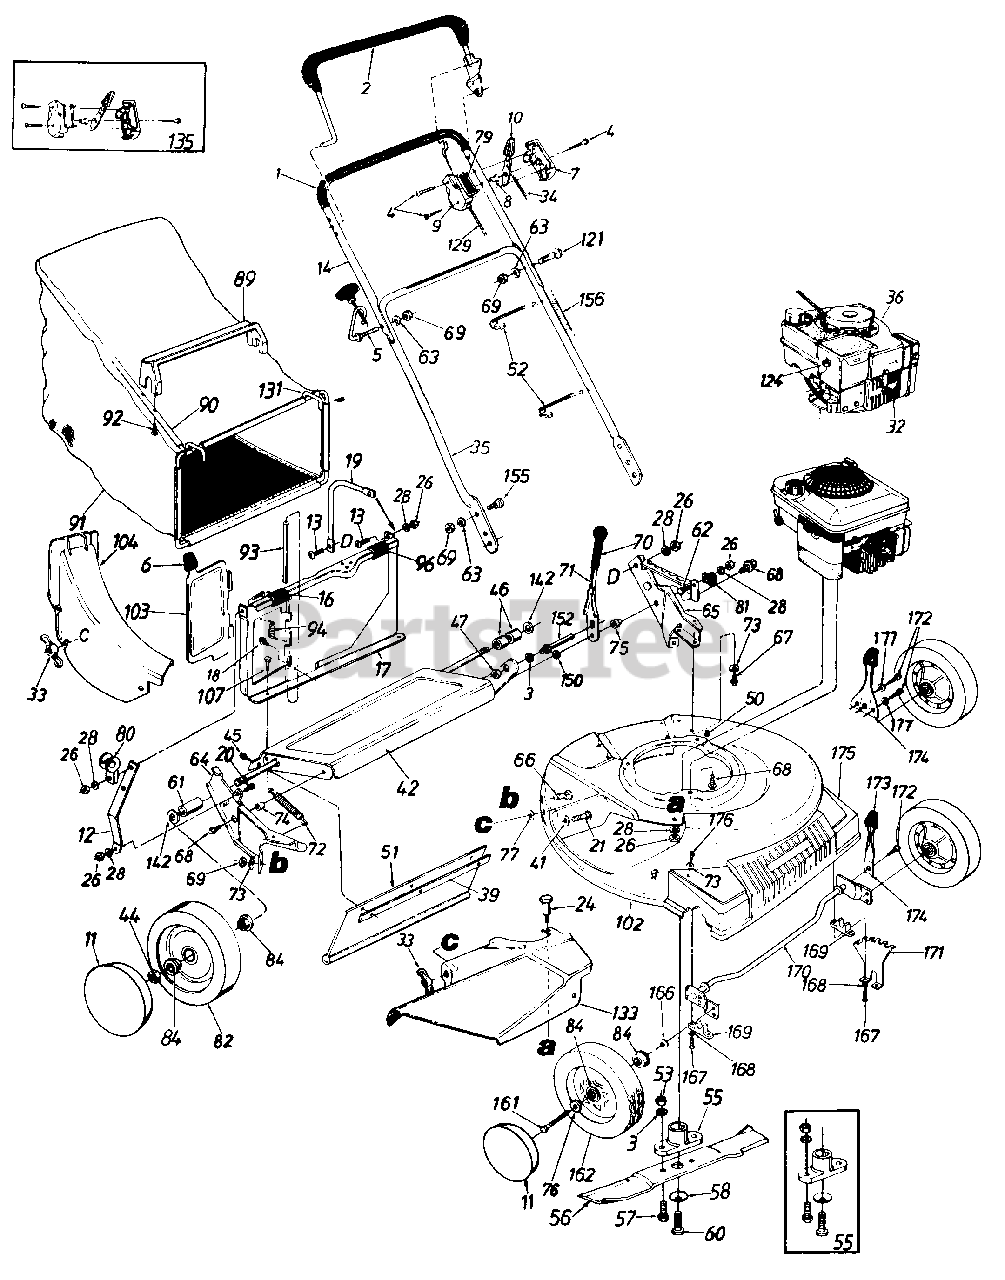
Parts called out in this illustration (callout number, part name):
1	Foam Grip
2	Control Handle Ass'y. L.H.
3	L-Wash. 3/8" I.D.
4	Truss Mach. Scr. #12 x 1.5"
5	Rope Guide Bolt
6	Door Grip
7	Control Panel Half
8	Control Disc Pin
9	Clutch Panel Half
10	Throttle Control Lever
11	Hub Cap
13	Truss Mach. Scr. 1/4-20 x .62"
14	Upper Handle
16	Truss Mach. Scr. 1/4-20 x .75"
19	Catcher Panel Support Arm
20	Hex Bolt 1/4-20 x .62" Lg.
21	Carriage Bolt 1/4-20 x .62"
24	Shoulder Bolt .312 Dia. x .18 Lg. Special
26	Hex Nut 1/4-20 Thd.
28	L-Wash. 1/4" I.D.
32	Spark Plug Insulator
33	Wing Nut w/Washer
34	Throttle Control Ass'y. Comp. 61"
35	Lower Handle
36	Engine
39	Retaining Strip
41	Fl-Wash. .344" I.D. x .62"
45	Hex AB-Tap Scr. 1/4 X .62"
46	Spacer.526" I.D.
47	Hex Jam Nut 3/8-24 Thd.
51	Rear Flap
52	Cable Tie
53	Hex Nut 3/8-24 Thd.
55	Blade Adapter Kit
56	21" Blade
57	Hex Bolt 3/8-24 x 1" Lg.
58	Bell-Wash. .46" I.D. x 1.12"
60	Hex Bolt 7/16-20 x 1.5" Grade 5
61	Sleeve.526" I.D.
62	Truss Mach. Scr. 1/4-20 x .75" Lg.
63	L-Wash. 5/16" I.D.
64	R.H. Handle Wheel Brkt. Ass'y.
65	L.H. Handle Wheel Brkt. Ass'y.
66	Carriage Bolt 5/16-18 x .62"
67	Hex B-Tap Scr. 5/16-18
68	Hex TT-Tap Scr. 3/8-16
69	Hex Nut 5/16-18 Thd.
71	Height Adj. Lever
72	Extension Spring 3.80" Lg.
73	Bell-Wash. 5/16" I.D.
74	Spacer.383" I.D.
75	Shld. Spacer.5" Dia.
76	Wave Wash. .53" I.D. x .78"
77	Bolt Retainer 1/4 x .50" O.D.
79	Control Label
80	Rope Guide
81	Clamp
82	Wheel Ass'y. Comp.
84	Flange Ball Bearing 1/2" I.D.
89	Bag Handle
91	Grass Bag
92	Hex AB-Tap Scr. #12 x 1.25" Lg.
93	Chute Rod .188" Dia.
94	Torsion Spring
96	Panel Clip
104	Top Discharge Chute Ass'y.
107	Hex Bolt 1/4-20 x .50" Lg.
121	Curved Carr. Bolt 5/16-18 x 1.75" Lg.
124	Hex Nut 3/8 x 16 Thd.
129	Control Cable 46"
133	Side Chute Deflector Ass'y.
135	Kit Control Housing Comp.
142	Fl-Wash. .510" I.D. x .75"
150	Fl-Wash. 3/8" I.D. x 1.0"
152	Shld. Pin 3/8-24 x 1.43" Lg.
155	Truss Mach. Scr. 5/16-18 x .75"
156	Plastic Tubing 24" Lg.
161	Front Axle Bolt
162	Wheel Ass'y. Comp.
166	Bell-Wash. .400" I.D. x .88
167	Hex B-Tap Scr. 1/4-20
168	L-Wash. 1/4" I.D.
169	Block Bushing
170	Axle Ass'y.
172	Hex TT-Tap Scr. 1/4-20 x .50"
173	Knob
174	Spring Lever (With 1 hole only)
175	Plastic Front End
176	Truss B-Tap Scr. 5/16 x .75"
177	Ext. L-Wash. 1/4" I.D.
